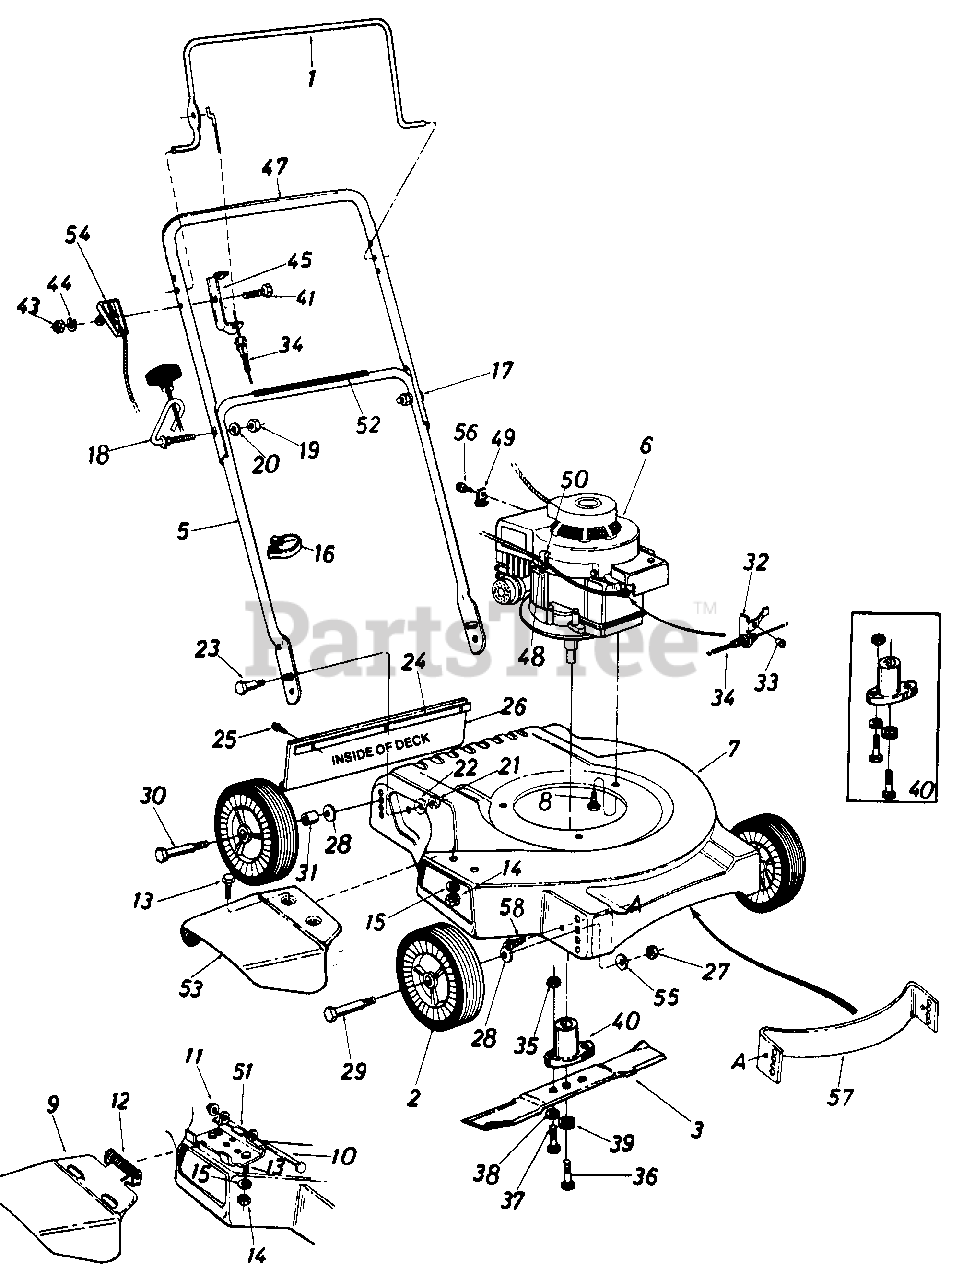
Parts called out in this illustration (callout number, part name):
1	Control Handle
2	Plastic Wheel Ass'y.
3	20" Blade
5	Lower Handle (Chrome)
6	Engine
8	Hex Wash. Hd. TT-Tap Scr. 3/8-16 x 1.00 Lg.
9	Chute Deflector Ass'y.
10	Pivot Pin
11	Cap Speed Nut 1/4" Rod
12	Torsion Spring
13	Hex Bolt 1/4-20 x .50" Lg.*
14	Hex Nut 1/4-20 Thd.*
15	L-Wash. 1/4" I.D.*
16	Cable Tie
17	Curved Carriage Bolt 5/16-18 x 1.38" Lg.
18	Rope Guide Bolt
19	Hex Nut 5/16-18 Thd.*
20	L-Wash. 5/16" I.D.*
21	Hex Ins. L-Nut 5/16-18 Thd.
22	Bell-Wash. .345" I.D. x .88" O.D.
23	Shld. Bolt .437" Dia. x .268" Lg.
24	Retainer Strip
25	Hex Wash. Hd. Self-Tap Scr. 1/4" x.62" Lg.
26	Rear Flap Ass'y.
27	Hex Nut 3/8-16 Thd.*
28	Bell-Wash. .400" I.D. x .88" O.D.
29	Shld. Bolt
30	Shld. Bolt
31	Spacer
32	Cable Bracket
33	Pop Rivet .156" Dia. x .379
34	Control Cable-43.0" Lg.
35	Hex Nut 5/16-24 Thd.*
36	Hex Bolt 3/8-24 x 1.00" Lg. (Grade 5)
37	Hex Bolt 5/16-24 x 1.00" Lg. (Grade 5)
38	L-Wash. 5/16" I.D.*
39	L-Wash. 3/8" I.D. Heavy Duty
40	Blade Adapter Kit
41	Hex Bolt 1/4-28 x 1.75" Lg.*
43	Hex Nut 1/4-28 Thd.
44	L-Wash. 1/4" I.D.
45	Cable Mounting Brkt.
47	Upper Handle (Chrome)
48	Hex B-Tap Scr. #10 x .38" Lg.
49	Casing Clamp
50	Casing Clamp
51	Hinge Plate
52	Instruction Label-Handle
53	Chute Deflector
54	Throttle Control Ass'y.-Comp.
55	Bell-Wash. .39" I.D. x 1.13" O.D.
56	Hex AB-Tap Scr. #8 x .38" Lg.
57	Baffle
58	Hex B-Tap Screw 1/4 x .38" Lg.
